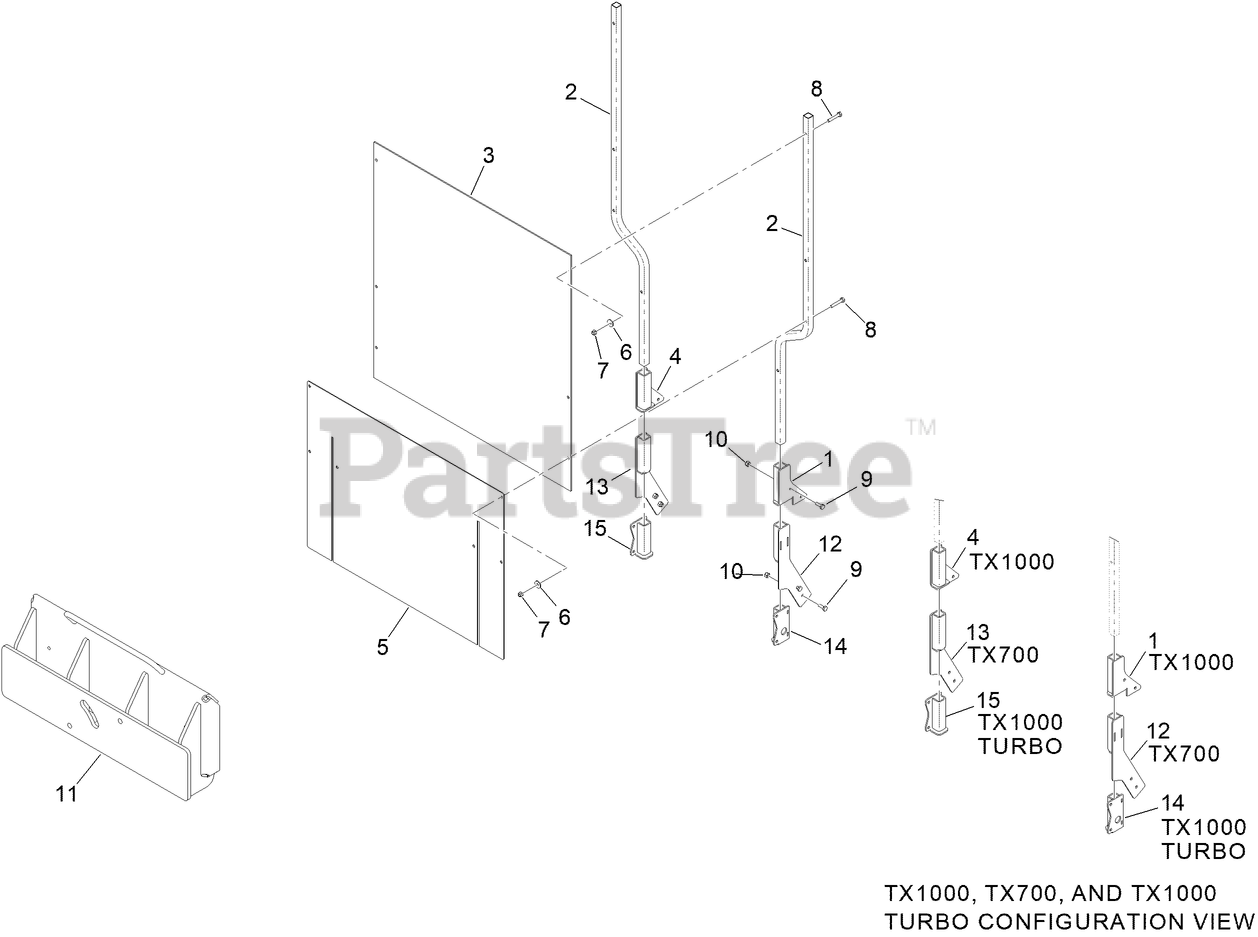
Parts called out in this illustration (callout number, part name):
1	BRACKET-SUPPORT, LH
2	SUPPORT-TUBE, SHIELD
3	SHIELD-LEXAN
4	BRACKET-SUPPORT, RH
5	SKIRT-PROTECTOR
6	WASHER-FLAT
7	NUT-HEX
8	SCREW-HH
9	SCREW-HH
10	NUT-LOCK, NI
11	PLATE-ATTACH, QUICK
12	BRACKET-SUPPORT LH
13	BRACKET-SUPPORT RH
